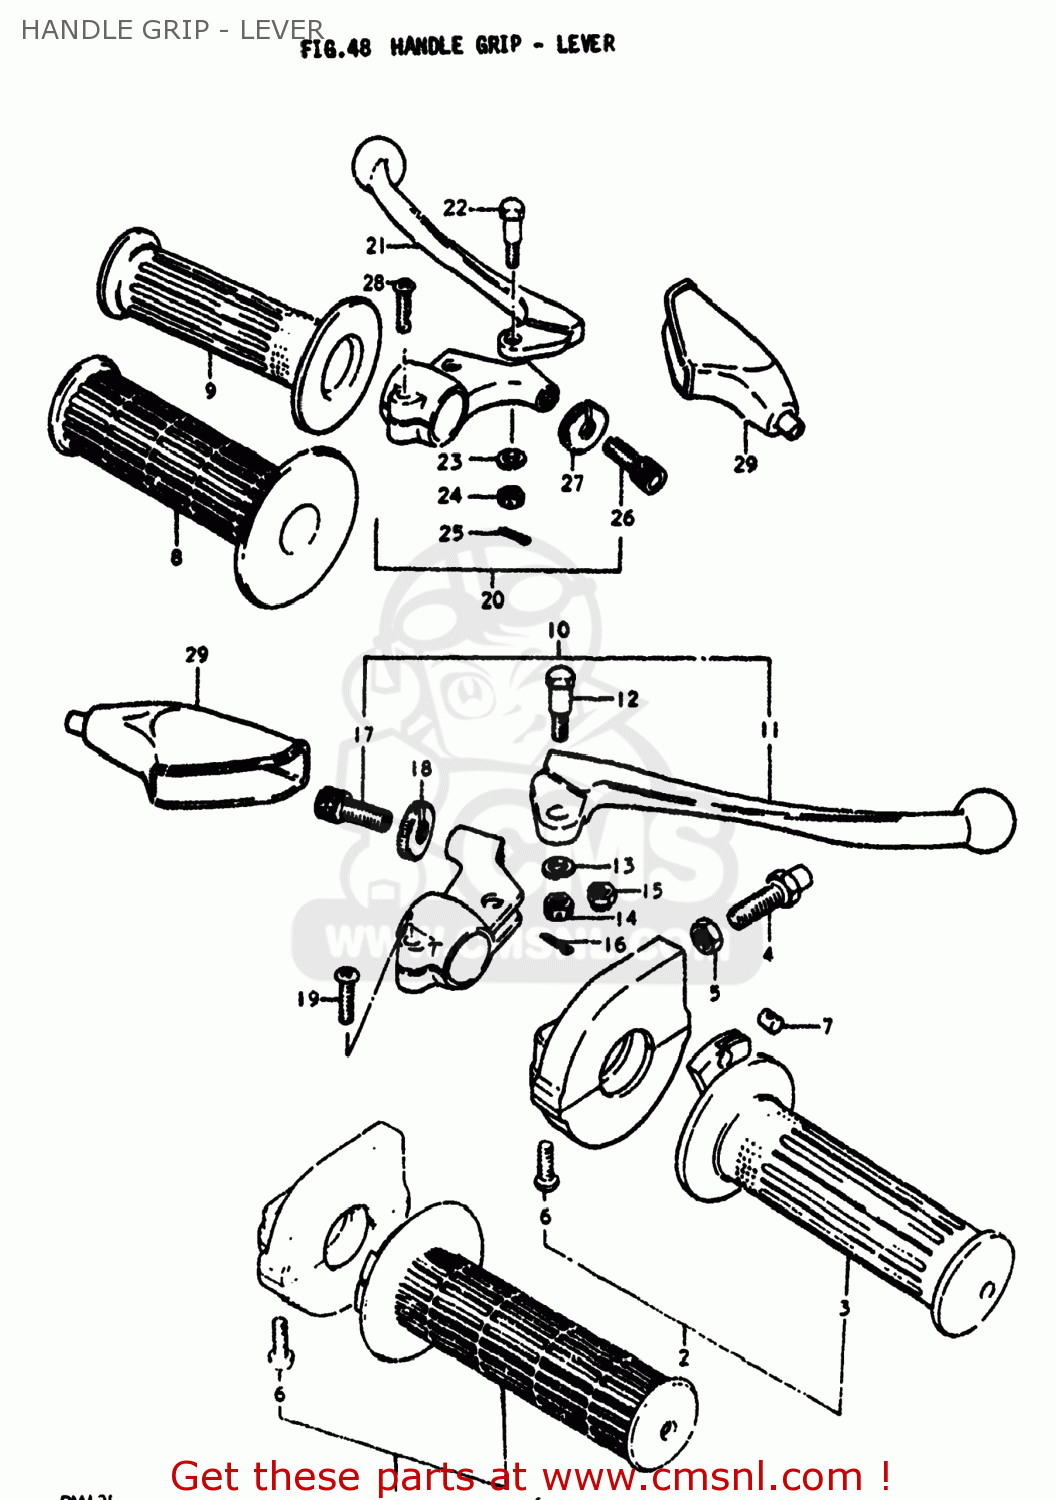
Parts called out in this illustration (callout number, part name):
1	CASE ASSEMBLY,THROTTLE
2	GRIP ASSY,THROTTLE
3	GRIP,THROTTLE
5	NUT
6	SCREW
7	PIECE,THROTTLE END
8	GRIP,LEFT
9	GRIP,LEFT
10	LEVER ASSY,BRAKE
11	LEVER,BRAKE
12	BOLT,LEVER
13	LOCK WASHER
14	NUT,LEVER FITTNG
15	NUT 6MM
16	COTTER PIN
17	ADJUSTER,CABLE
18	NUT,CABLE ADJUSTER
19	SCREW
20	LEVER ASSEMBLY
21	LEVER,CLUTCH
22	BOLT,LEVER
23	LOCK WASHER
24	NUT,LEVER FITTNG
25	COTTER PIN
26	ADJUSTER,CABLE
27	NUT,CABLE ADJUSTER
28	SCREW
29	COVER,CLUTCH LEVER
